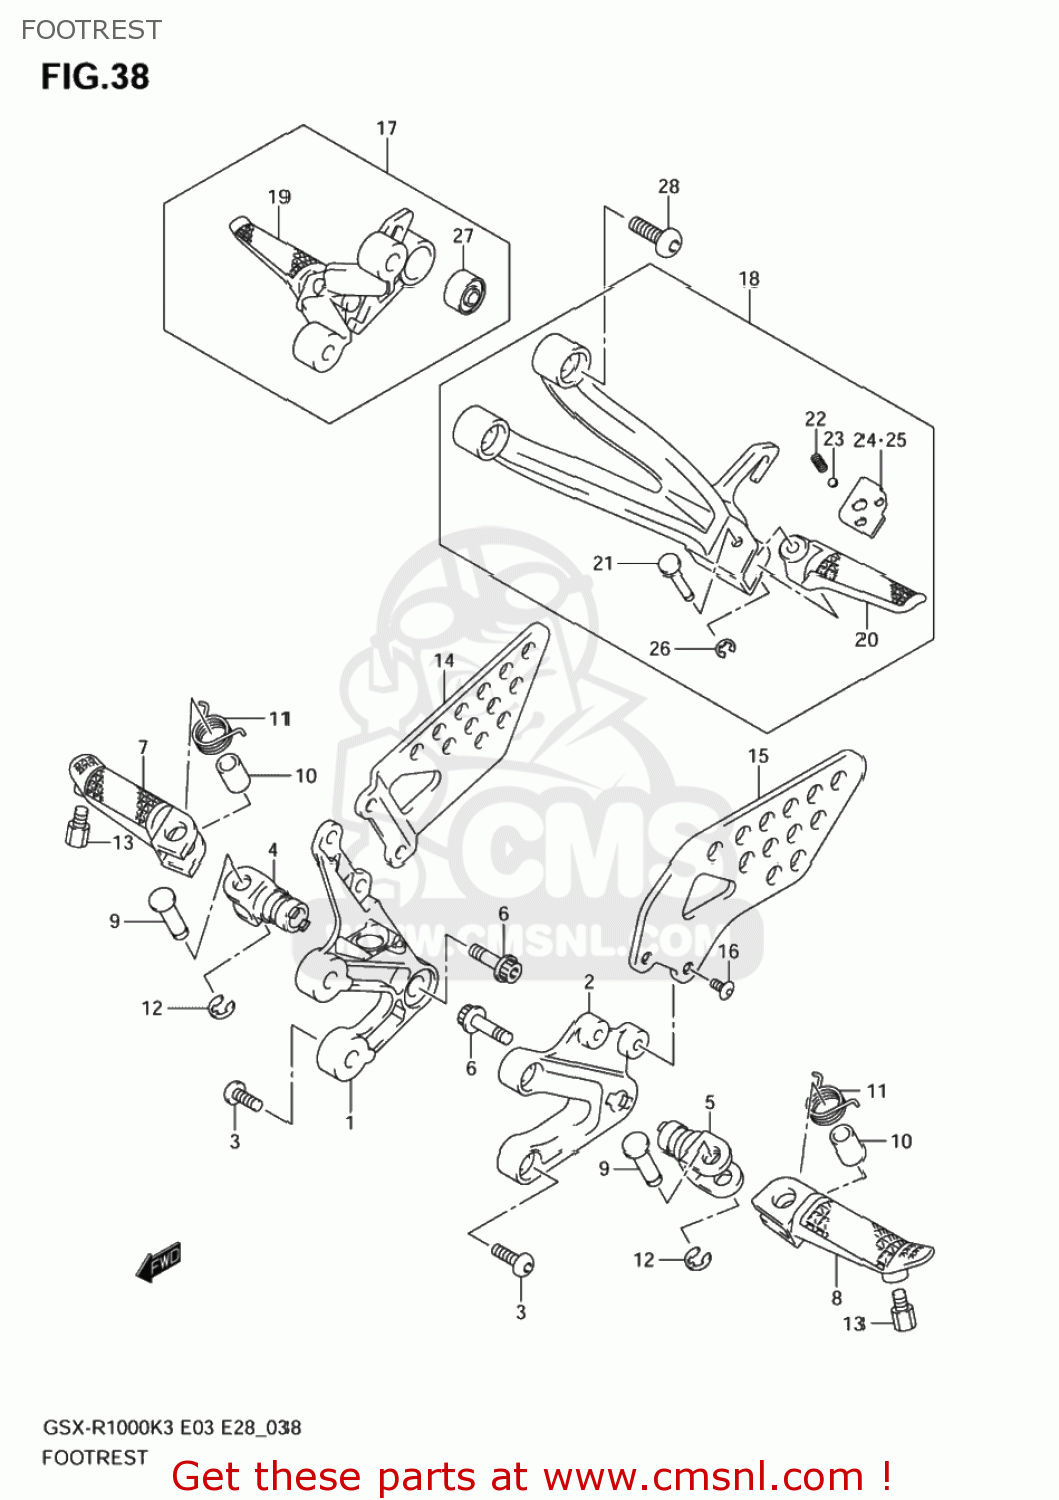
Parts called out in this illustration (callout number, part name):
1	BRACKET,FR FOOTREST,R
2	BRACKET,FR FOOTREST,L
3	BOLT(8X23)
4	HOLDER,FOOTREST,R
5	HOLDER,FOOTREST,L
6	BOLT(10X28)
7	BAR,FR FOOTREST,R
8	BAR,FR FOOTREST,L
9	PIN
10	SPACER(8.1X12X22)
11	SPRING
12	E.RING
13	BOLT,BANK SENSOR
14	GUARD,FR FOOTREST,R
15	GUARD,FR FOOTREST,L
16	SCREW(5X10)
17	FOOTREST ASSY,PILLION,R
18	FOOTREST ASSY,PILLION,L
19	BAR,PILLION FOOTREST,R
20	BAR,PILLION FOOTREST,L
21	PIN
22	SPRING
23	BALL
24	PLATE,PILLION FOOT,R
25	PLATE,PILLION FOOT,L
26	E-RING
27	BUSH
28	BOLT(8X23)
